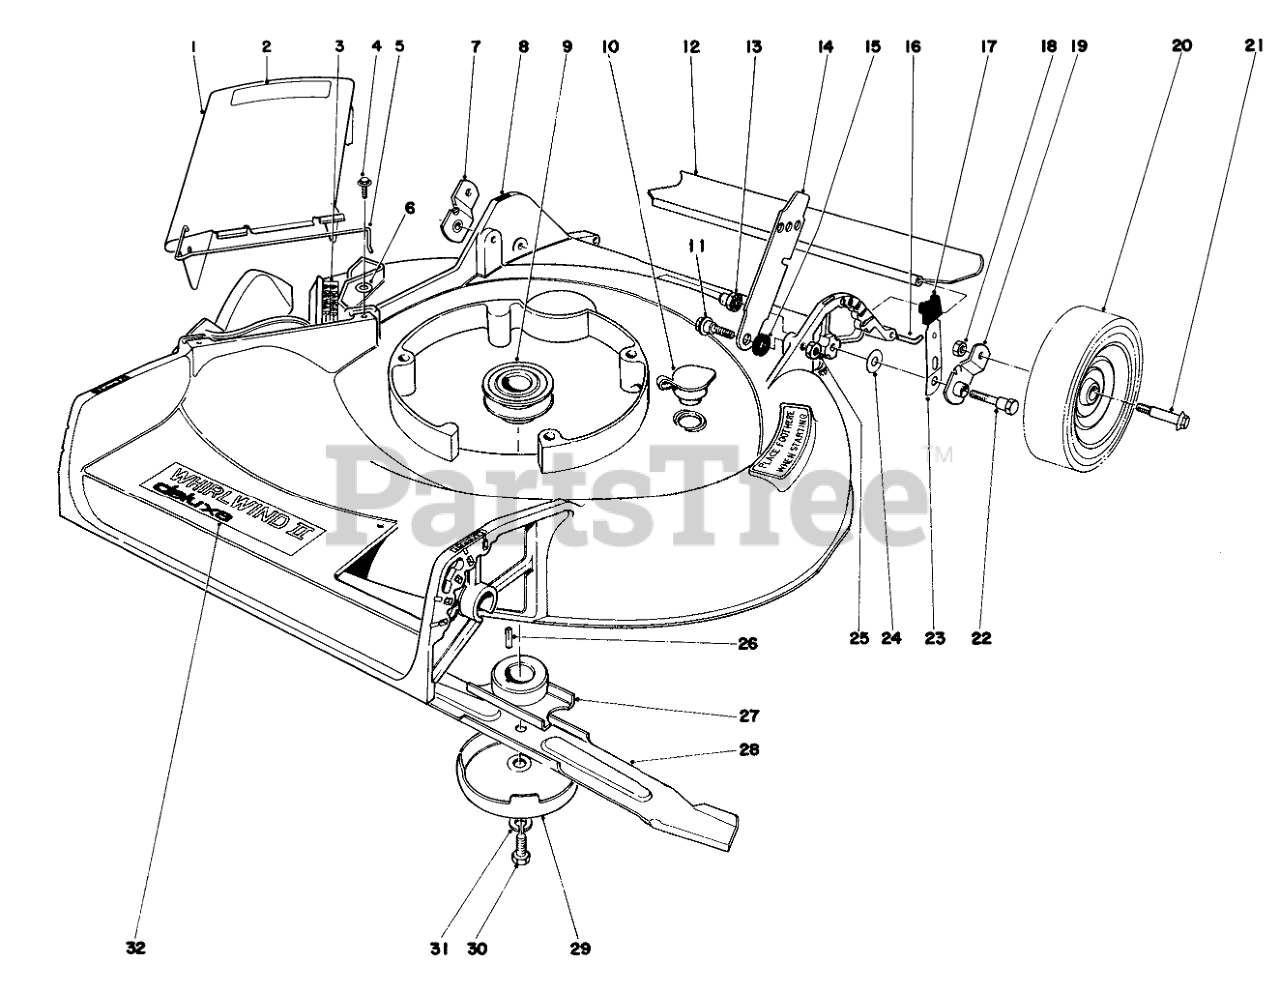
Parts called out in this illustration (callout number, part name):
1	Deflector Cover Assembly (Incl. Ref. #2 & 5)
2	Decal-Caution (French & Dutch)
3	Decal-Danger (French & Dutch)
4	SCREW
5	SPRING HINGE
6	WASHER-FLAT
7	Pivot Arm
8	Housing
9	DRIVER PULLEY
10	WASHOUT PLUG
11	SCREW-SHOULDER
12	REAR SAFETY SHIELD 21
13	HANDLE PIVOT NUT
14	Latch
15	HANDLE LATCH SPACER
16	SHIELD ROD
17	KNOB-ARM
18	Nut
19	Pivot Arm
20	Wheel Assembly
22	5/16-18 PIVOT SCREW
23	SPRING ARM ASM
24	WASHER-PIVOT
25	Nut
26	KEY-SQUARE
27	Blade Retailer
28	Blade
29	AntiScalp Cup
30	SPECIAL SCREW
31	WASHER-LOCK
32	Decal Deck
